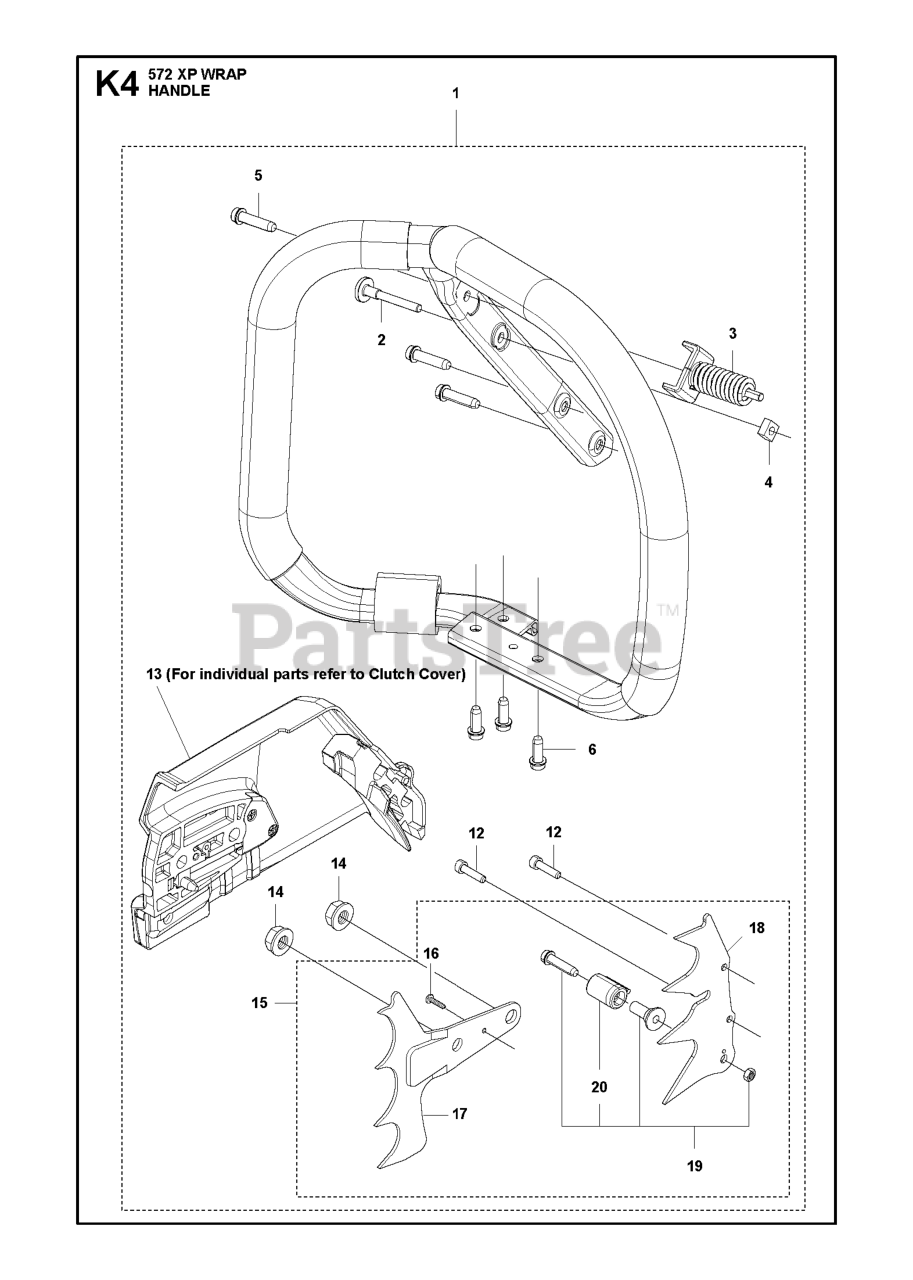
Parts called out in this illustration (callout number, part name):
1	FRONT HANDLE ASSY KIT WRAP STA
2	SCREW ITXPANM MOVEMENT LIMITER
3	ANTIVIBRATION ELEMENT CYLINDER
12	SCREW ITXSCM
13	CLUTCH COVER ASSY
14	NUT M8 FLANGE
15	SPIKE KIT WESTCOAST H565/H572
17	FELLING DOG
18	FELLING DOG
19	CHAIN CATCHER H565/H572 KIT
